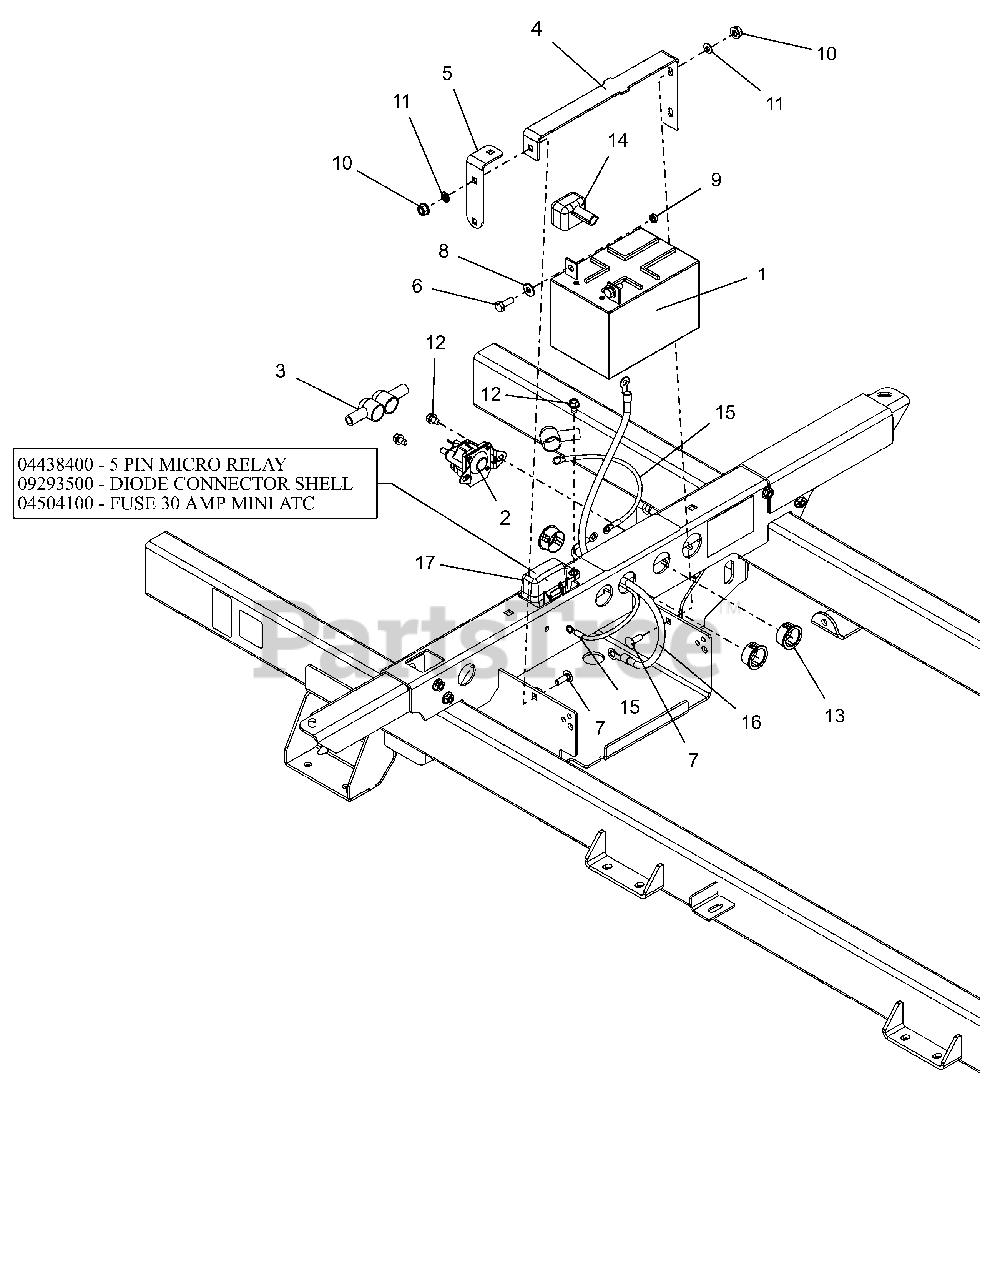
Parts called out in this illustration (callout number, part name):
1	BATTERY, 12V 12A-190CCA
2	SOLENOID, STARTER (SEALED)
3	BOOT, EYELET TERMINAL
4	BRKT, BATTERY HOLD-DOWN
5	BRKT, BATTERY HOLD DOWN
6	@BLT-HEX .25-20X.75 GR5 YWZC
7	@BLT-RDHDSQNK .25-20X.75 G5YZ
8	@WSHR-FL-STL.281X.62X.065 YWZC
9	NUT, 10-24 KEPS
10	@NUT-LK-TOP-FLG .25-20 YWZC
11	NUT-PUSH .25X.50 O.D.
12	@SCR-TAP .25-20X.37 HWH YWZ TR
13	BSHG, PANEL SNAP .937X1.11X.56
14	INSULATOR
15	CABLE,POS W/2 1/4 RING 15.0 LG
16	CABLE-NEGATIVE BATTERY 24.00"
17	HARNESS, WIRE-4POS KEY IKON/ZT
17	RELAY,MICRO5 TERML W/RESISTOR
17	DIODE, CONNECTOR SHELL
17	FUSE,30 AMP MINI-ATC
